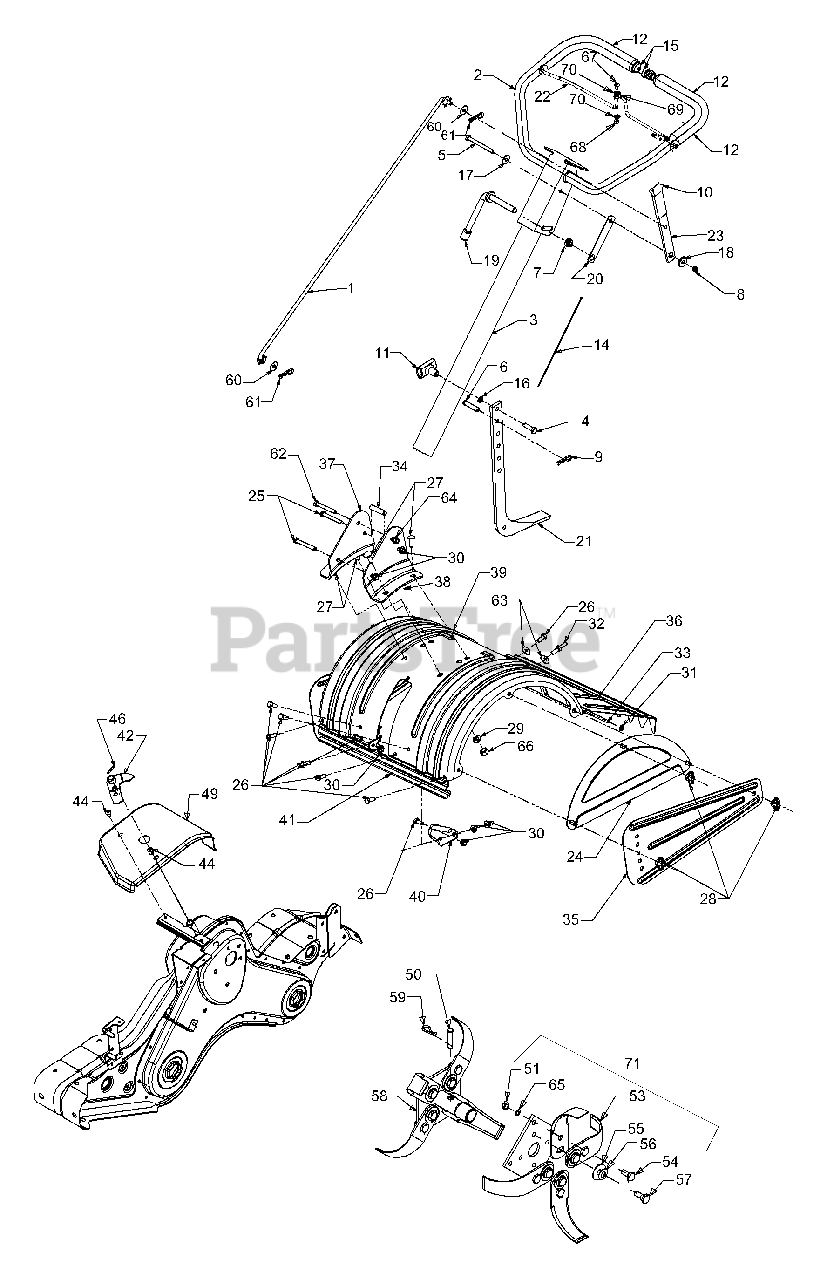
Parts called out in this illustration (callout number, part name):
1	Shift Rod
4	Hex Screw 3/8-16 x 1.25
5	Hex Screw 5/16-18 x 3.25
6	Clevis Pin 3/8-1.62
7	Flange Lock Nut 3/8-24
8	Hex Lock Nut 5/16-18
9	Cotter Pin
11	T-Knob
12	Foam Grip
14	Cable Tie
16	Flat Washer 3/8 x.620 x.033
17	Bell Wash.340 I.D. x.872 O.D.
18	Shoulder Spacer
19	Handle Adjustment Crank
20	Hex Nut Ret. Bracket
21	Depth Stake
22	Bail Clutch
25	Hex Cap Screw 5/16-18 x 2.75
26	Hex Cap Screw 5/16-18 x.750
27	Carriage Bolt 3/8-16 x 1.0
28	Wing Nut
29	Lock Washer 3/8
30	Flange Nut 5/16-18
31	Cap Nut
32	Hex Screw 5/16-18 x.75" Lg.
33	Tiller Flap Rod
34	Spacer.435 O.D. x.322 I.D.
40	Tine Shield Brkt.
41	Tine Shield Scraper Bracket
42	Shift Crank Ass'y
44	Screw 1/4-14 x.625
46	Spirol Pin 3/16 x 1.00
51	Hex Nut 3/8-24 Thd.
53	13" Dia. Articulating Tine
54	Shld. Bolt 1/2" DIa. x.175
55	Fl-Wash.51" I.D. x 1.50"
56	Bell-Wash.515" I.D. x 1.14"
57	Shld. Bolt 1/2" Dia x.320
58	Tine Adapter Ass'y 18"
59	Internal Cotter Pin
60	Rubber Washer
61	Cotter Pin
62	Hex Screw 3/8-16 x 2.75" Lg.
63	Flat Washer
64	Flange Nut.344 I.D. x.62 O.D.
65	Lock Washer
66	Hex Nut 3/8-16
67	Truss Screw 1/4-20 x.65
68	Hex Lock Nut 1/4-20 Gr. 8
69	Battery Hose Clamp 5/16
70	Flat Washer.260 x.720 x.060
71	Tine Ass'y Complete
